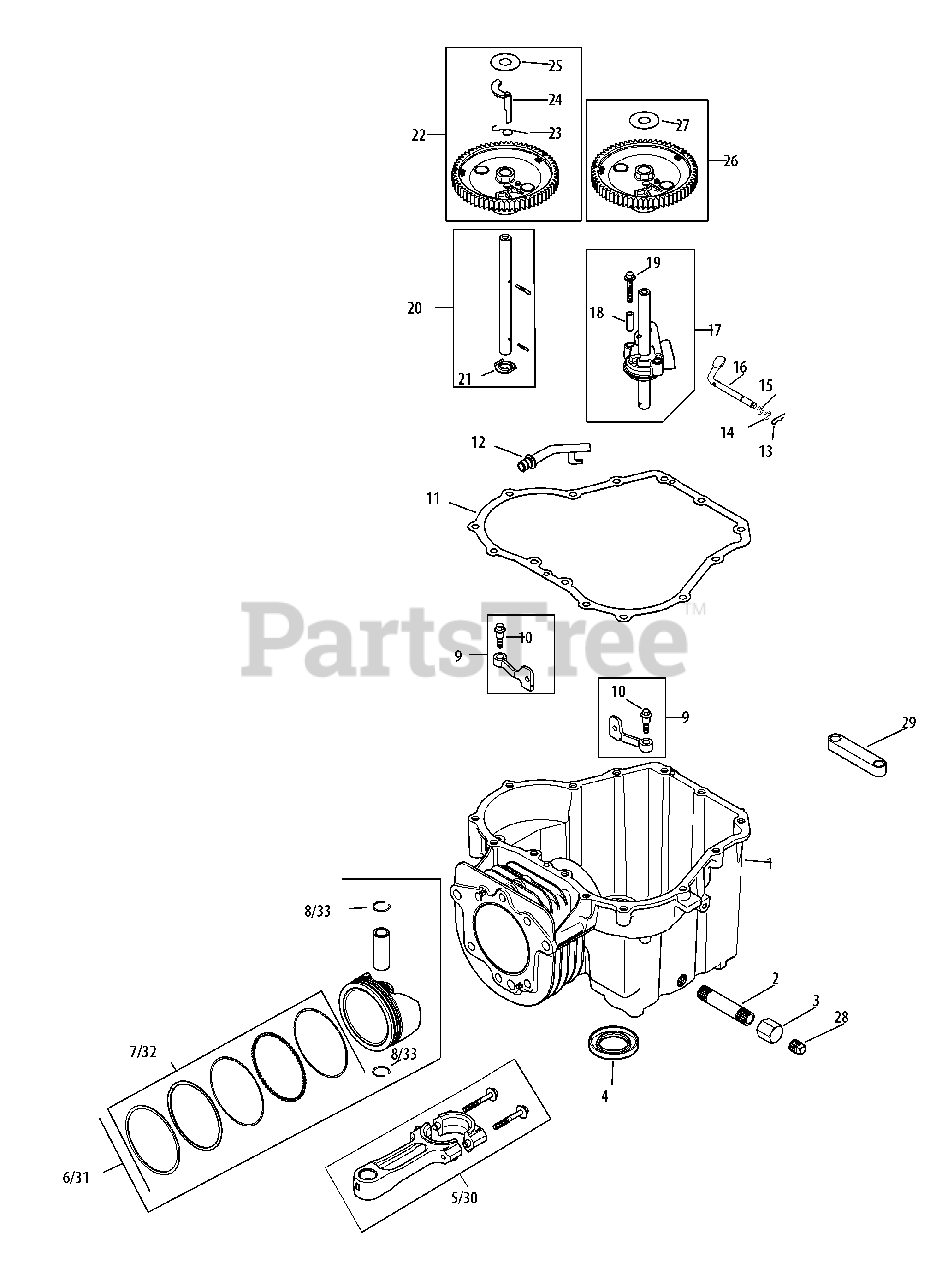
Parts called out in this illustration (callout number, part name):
1	Crankcase (Use: Short Block)
5	Connecting Assembly Rod
6	Piston w/ Ring Set, 94mm (Incl. 7, 8)
8	Piston Pin Retainer
10	Shd. Thd. Frm. Screw, M6 X 1 X 26
12	Drainback Tube
13	Hitch Pin Clip
14	Flat Washer, 6 Mm
15	Flat Washer, 1/4
16	Governor Cross Shaft
17	Oil Pump Ass’y Kit (Incl. 11, 18, 19)
19	Oil Pump Screw
20	Cam Center Shaft Kit (Incl. 21)
21	Thrust Washer
22	Camshaft Ass’y Kit (Incl. 23-25)
25	Thrust -Acr. Washer
26	Camshaft Ass’y Kit (Incl. 27)
27	Thrust -Acr. Washer
28	Square Head Pipe Plug, 3/8
